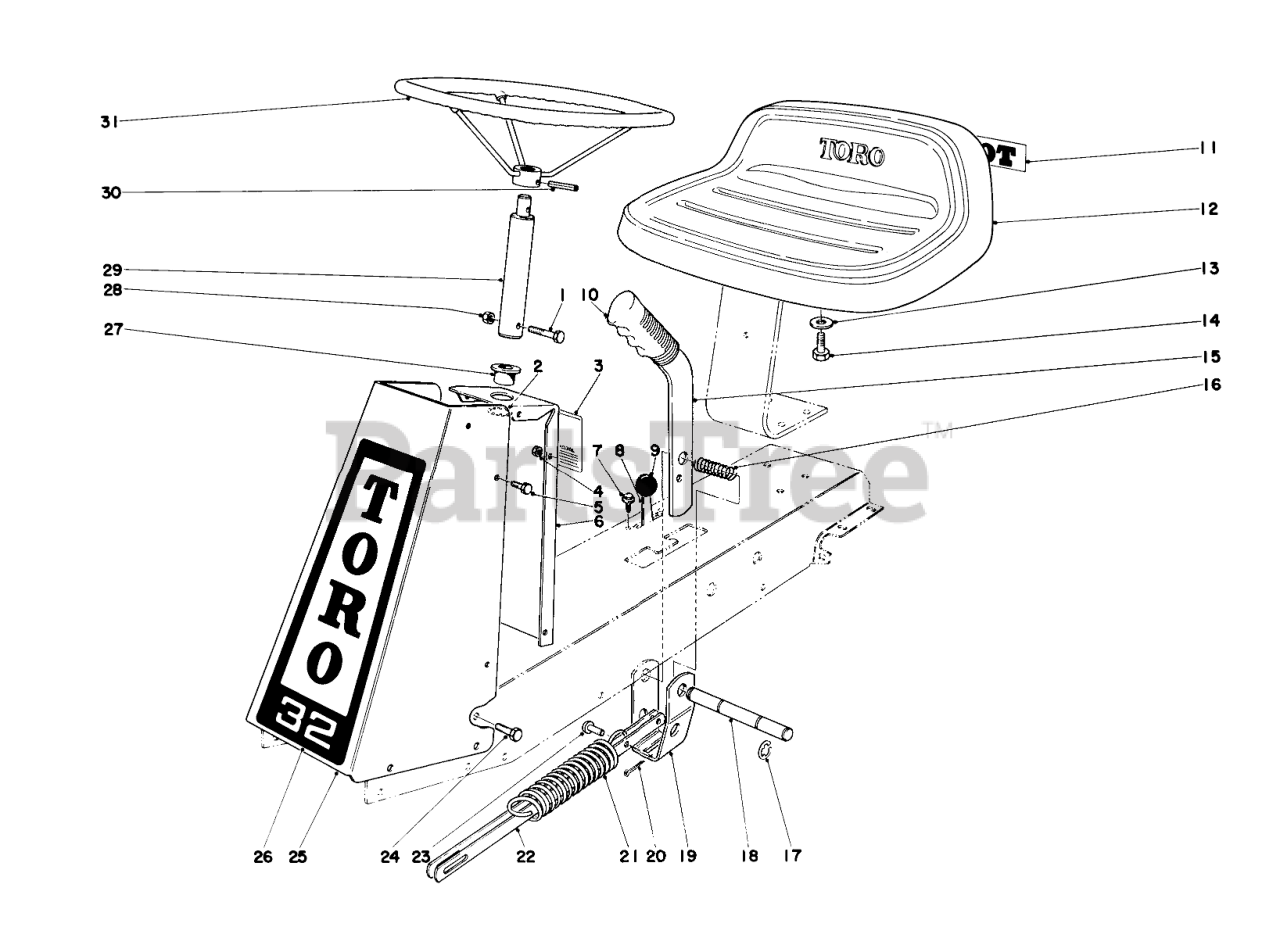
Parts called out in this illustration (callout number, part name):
1	Capscrew
2	Retaining Ring
3	Decal-Caution
4	NUT-LOCK, CONE
5	SCREW-HH
6	Panel Assem. (Incl. Ref. Nos. 2 & 27)
7	Screw
8	Throttle Control
9	KNOB-CONTROL
10	Grip Handle
11	Decal
13	WASHER-FLAT
14	HEX HD CAPSCREW
15	Blade Clutch Handle
16	Spring
17	E-RING
18	Blade Handle Shaft
19	Clutch Handle Pivot
20	PIN-COTTER
21	Spring
22	Tie Bar Blade Clutch
23	PIN-CLEVIS
24	SCREW-HH
25	Cover, Steering Column
26	Decal
27	Bushing
28	NUT-LOCK, CONE
29	Shaft Steering
30	PIN-ROLL
31	Steering Wheel
